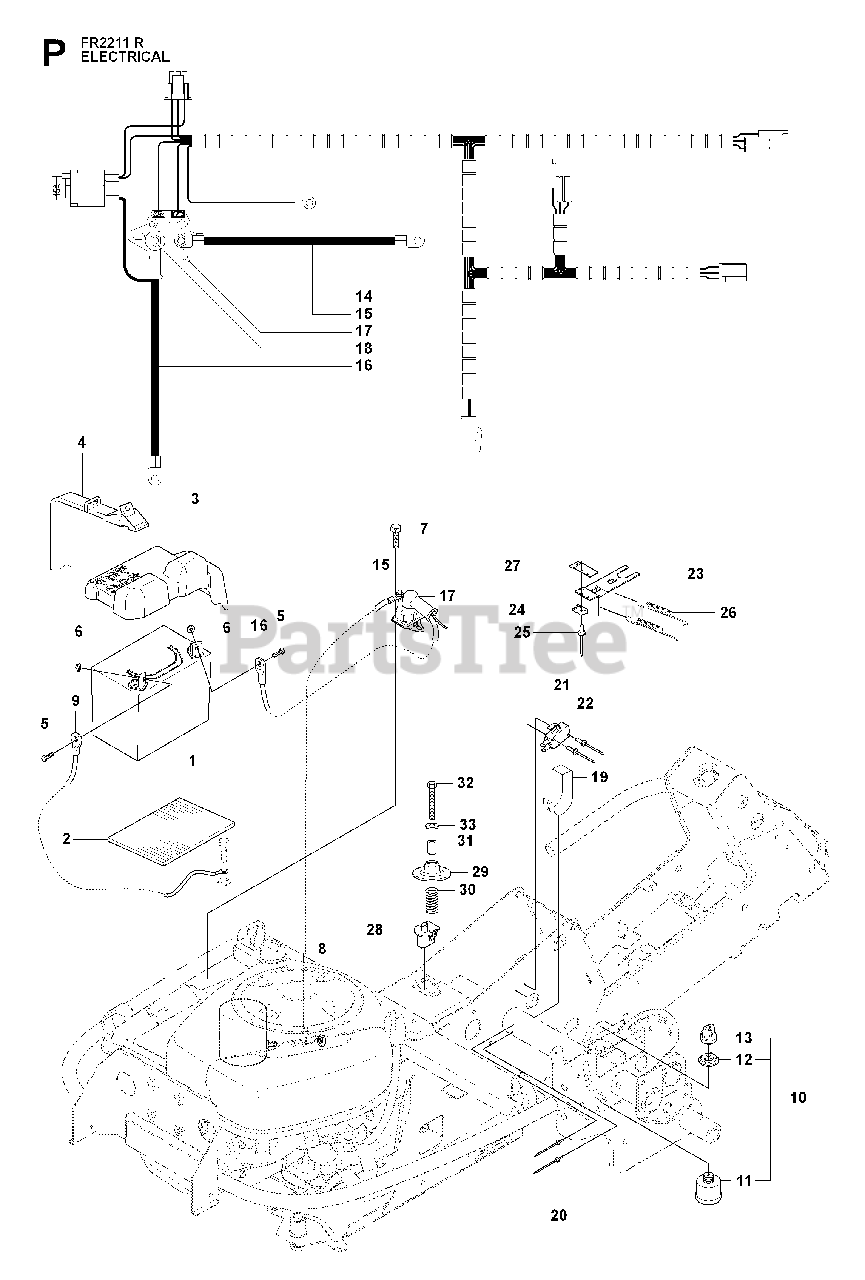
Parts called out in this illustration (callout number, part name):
5	SCREW EHHM
10	IGNITION SWITCH
11	IGNITION SWITCH
13	IGNITION KEY
21	%BRAKER
24	%BRAKER
26	SPRING
31	SPACER TUBE
32	SCREW
33	WASHER BRB 8.4X17
